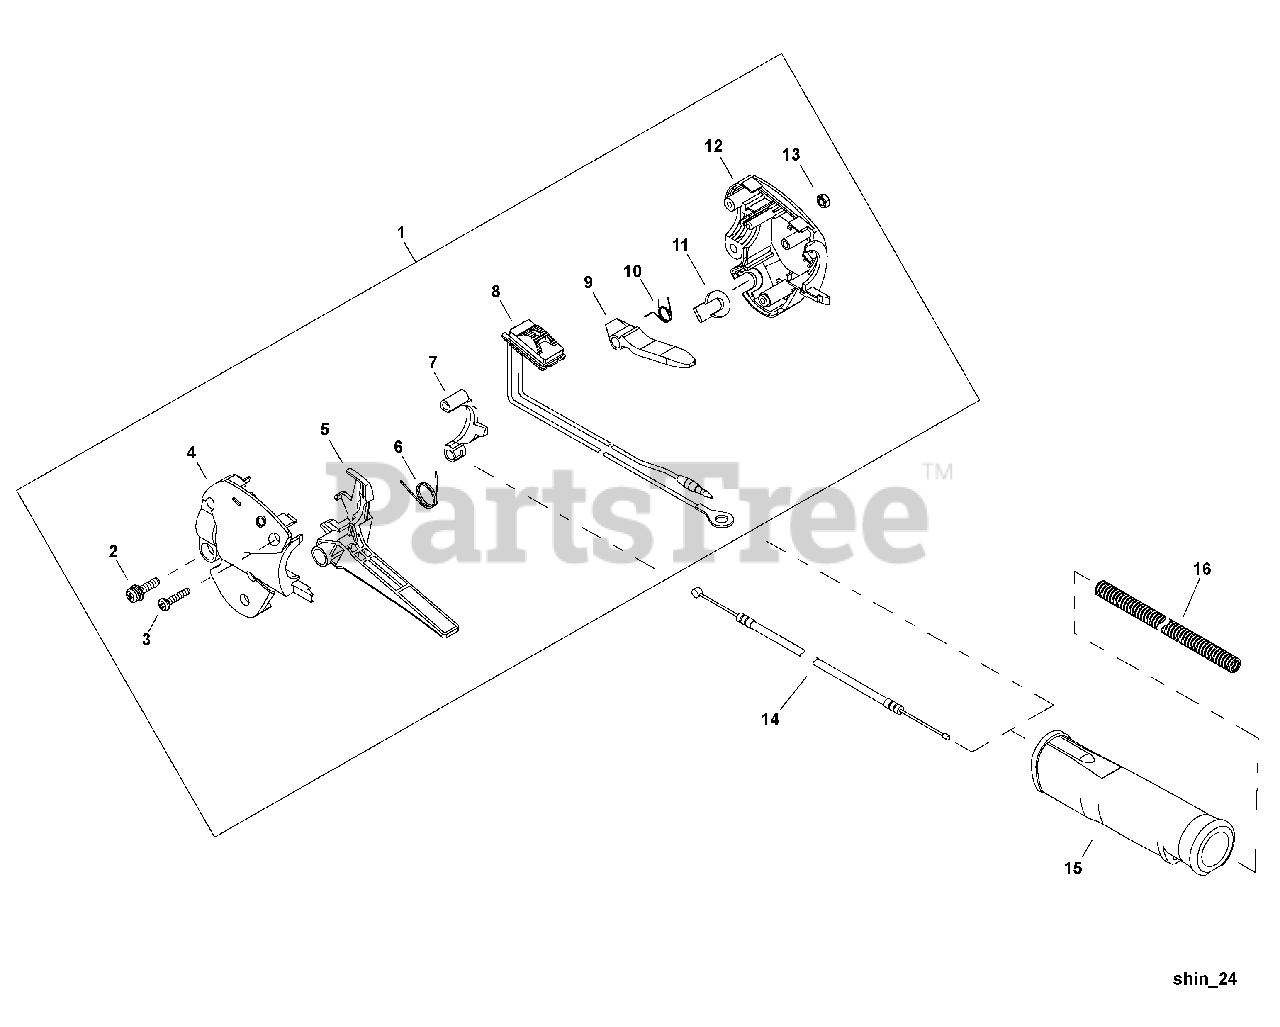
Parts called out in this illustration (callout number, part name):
1	THROTTLE CONTROL ASSY
2	SCREW - 5X20
3	SCREW - 4X20 -- TAPPING
4	HANDLE, CONTROL - LEFT
5	TRIGGER, THROTTLE
6	SPRING
7	LOCKOUT, THROTTLE
8	SWITCH, IGNITION
9	LEVER, TRIGGER LOCKOUT
10	SPRING
11	PLUG
12	HANDLE, CONTROL - RIGHT
13	NUT - 5
14	CABLE, THROTTLE
15	GRIP, THROTTLE CONTROL
16	TUBE
